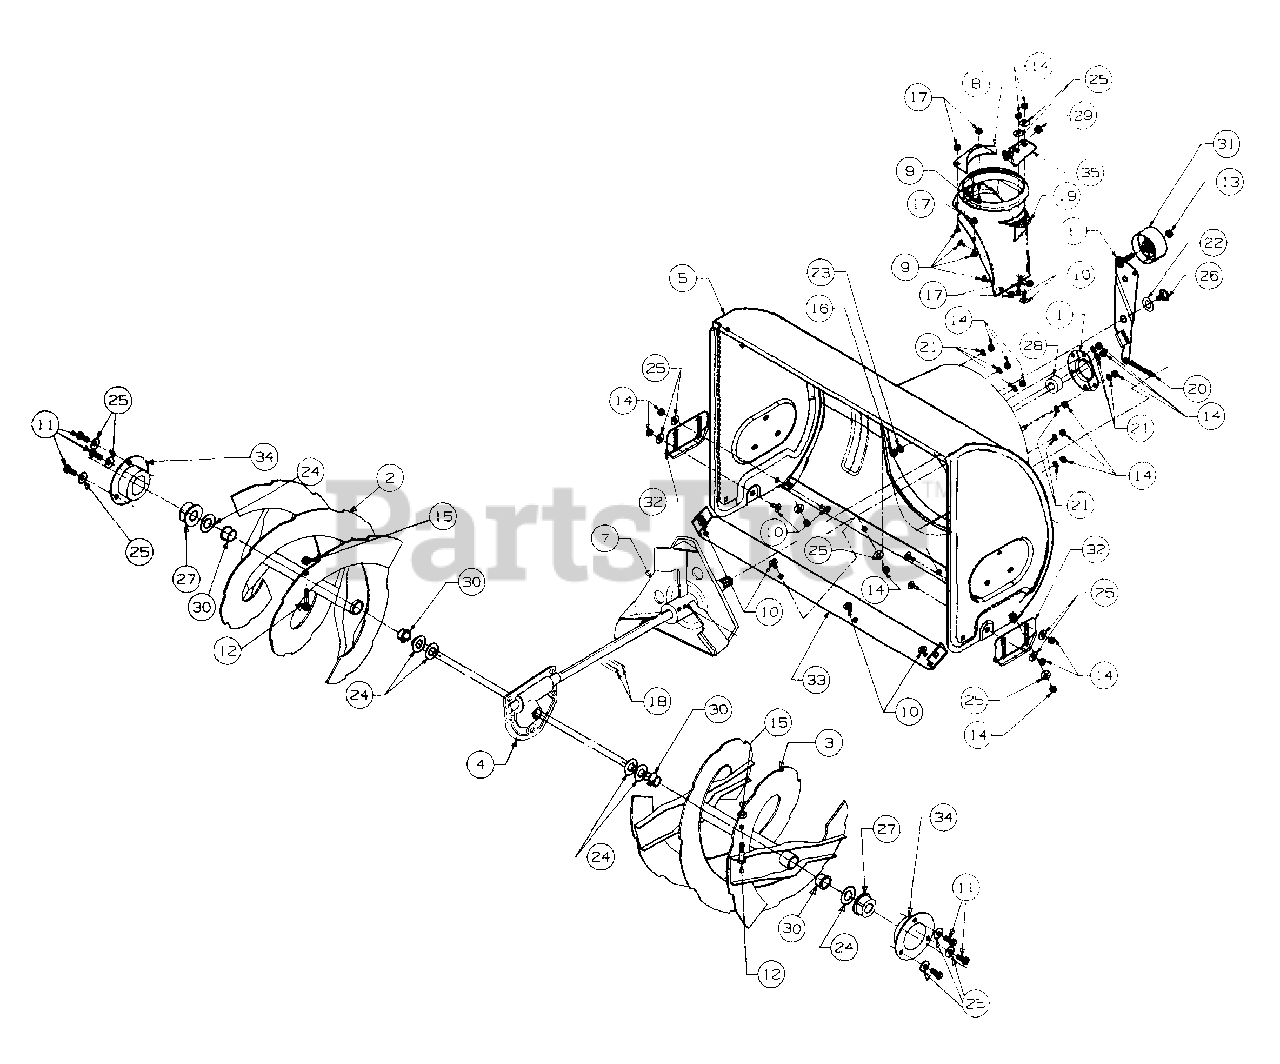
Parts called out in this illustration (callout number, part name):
1	Housing-Bearing
2	Spiral Assembly - L.H.
3	Spiral Assembly - R.H.
4	Gear Assembly
5	Housing Assembly
6	Arm - Idler Assembly
7	Impeller Assembly
9	Carriage Screw
10	Carriage Screw
11	Hex Screw
12	Shear Bolt
13	Hex Lock Nut
14	Hex Nut
15	Hex Nut
16	Hex Nut
17	Hex Lock Nut
18	Pin - Spring
19	Adapter - Chute
20	Spring
21	Lock Washer
22	Flat Washer
23	Lock Washer
24	Flat Washer
25	Bell Washer
26	Shoulder Screw
27	Flange Bearing
28	Ball Bearing
29	Plastic Bushing
30	Flange Bushing
31	Flat Idler
32	Slide Shoe
33	Shave Plate
